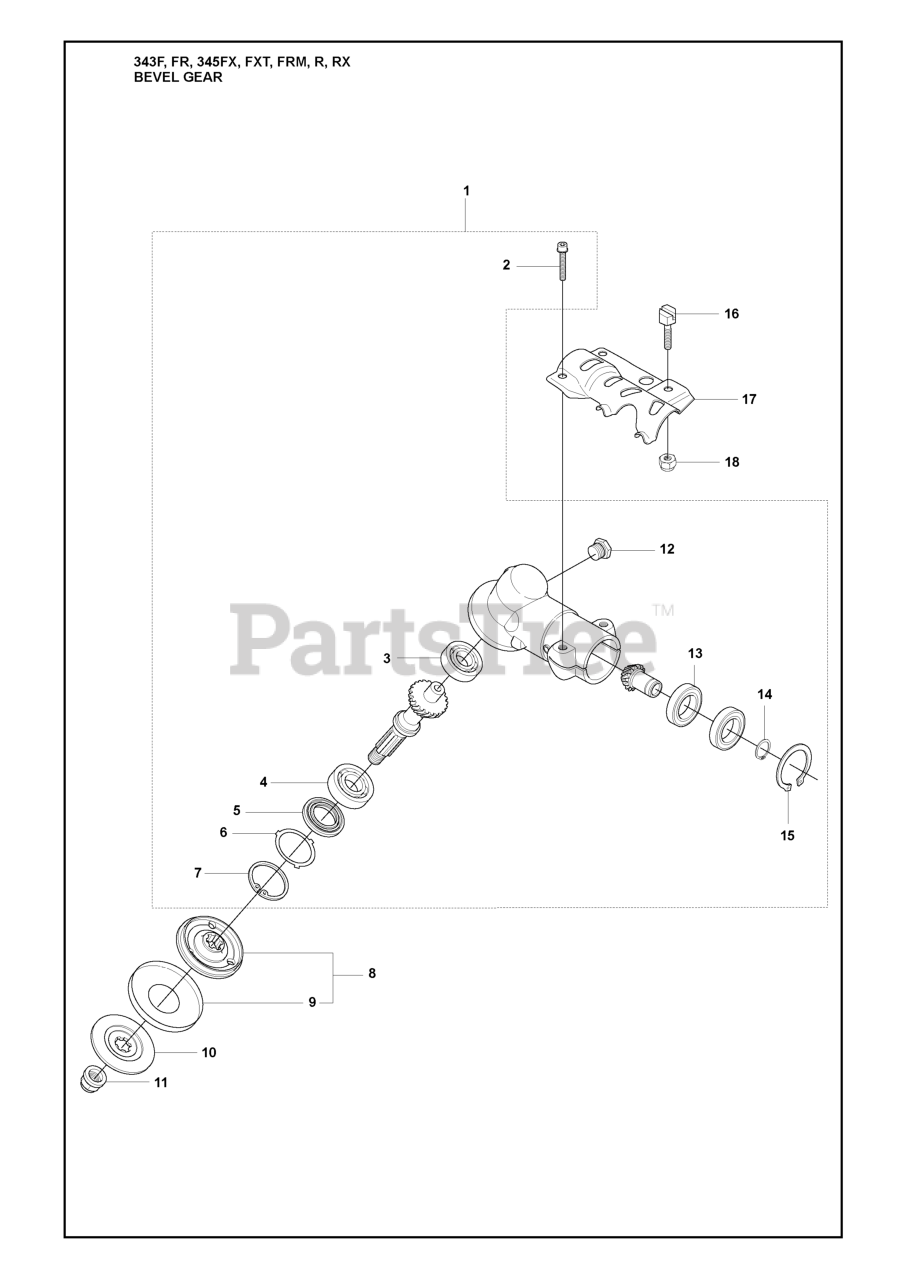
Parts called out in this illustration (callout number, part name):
1	GEAR ASSY
3	BALL BEARING
4	BALL BEARING
7	RETAINING RING SGH 35
8	RP CARRIER
9	RP TUBE INSERT
10	SUPPORT FLANGE
13	BALL BEARING
14	RETAINING RING SGA 15
15	RETAINING RING
17	BRACKET
18	LOCKNUT M6
